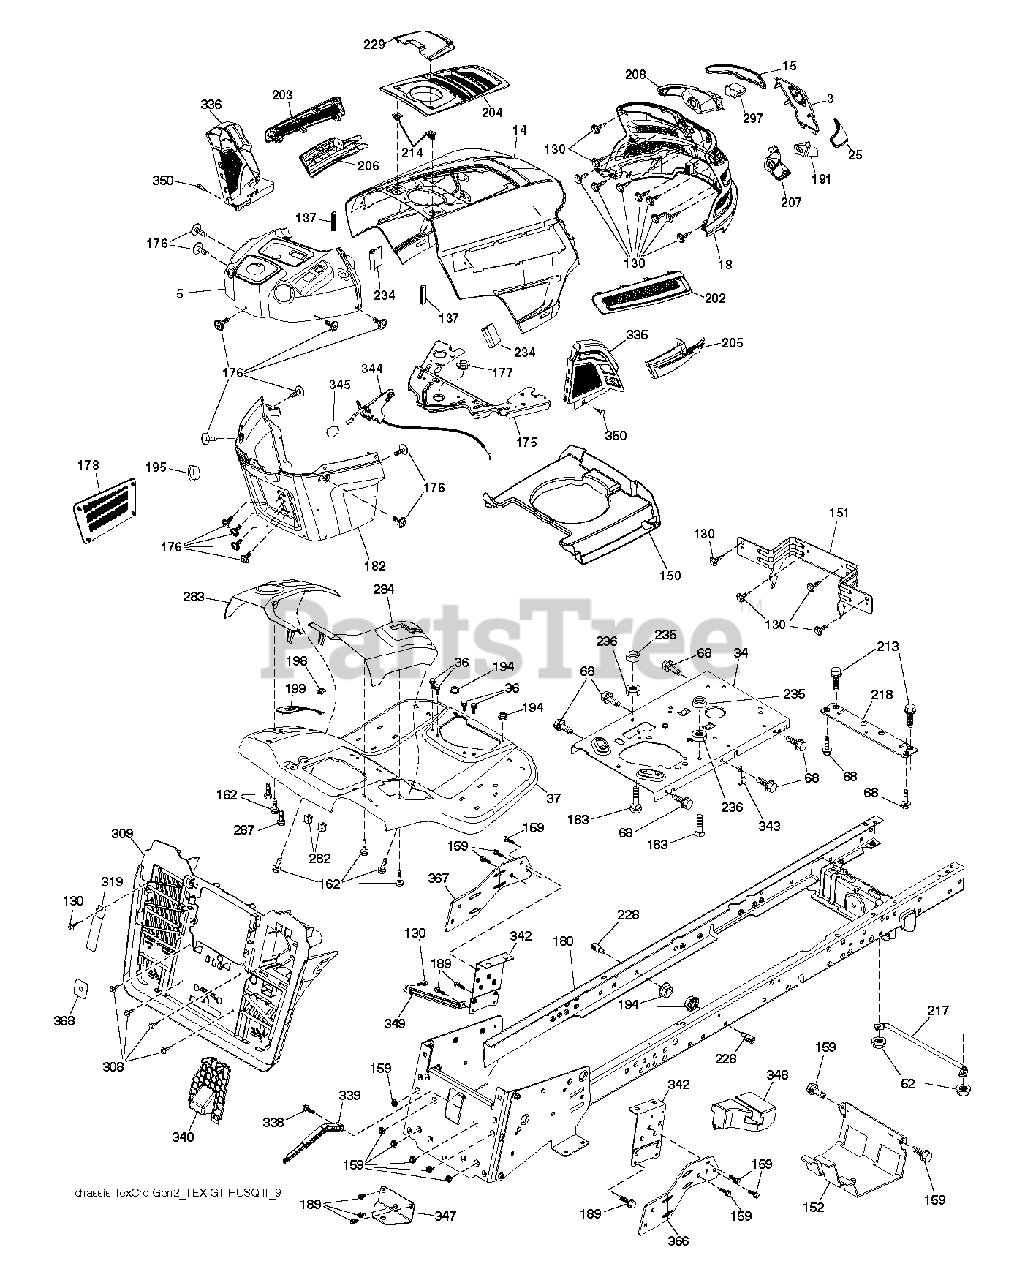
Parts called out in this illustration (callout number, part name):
3	APPLIQUE.SUBASM.GT.HUSQ.II
14	HOOD.ASM.HUSQVARNA.GT.TEX.ORAN
15	LENS.HEADLIGHT.LH.GTII.2011
18	GRILLE.SUBASM.GT.HUSQ.II
25	LENS.HEADLIGHT.RH.GTII.2011
34	PLATE.ENGINE.WELDED.CHASSIS
36	SCREW 5/16"
37	FENDER.TEX.SRD.CRD.BASE
52	LOCKNUT
68	SCREW LT
130	SCREW.#10 X 0.750.BOS
137	BUMPER DASH
150	AIR.DUCT.GTV.BLACK
151	BRACKET.PIVOT.HOOD.GT.HUSQ.II
152	SHIELD.BROWNING.PNT.GT.V2
159	SCREW, 3/8-16X3/4
162	SCREW.HI-LO.CONSOLE
175	PLATE.CROSSMEMBER.HUSQ
176	SCREW.#10-24X5/8.RN.QU
177	BUSHING, STEERING
178	CARGO.ASM.NET.TXGT.W/C
182	DASH DASH LOWER
183	BOLT.5/16-18X1-1/4 FULL THD
189	SCREW
191	INSERT.REFLECTIVE.RH.HUSQ.GTII
194	NUT LOCK HEX FLANGE 5/16-18
195	PLUG.HOLE.DASH.LOWER.12V.BLK
198	INDICATOR.DECK.LIFT.RED
199	PLATE DECK LIFT
202	VENT.SIDE.RH.GT.HUSQ.II.
203	VENT.SIDE.LH.GT.HUSQ.II.498
204	VENT.TOP.EXTERNAL.FILL.GT2.GRE
205	SIDE.TRIM.RH.GT.HUSQ.II
206	SIDE.TRIM.LH.GT.HUSQ.II.GRAY
207	BEZEL LIGHT.RH.GT.II.MYLAR
208	BEZEL LIGHT.LH.GT.II.MYLAR
213	BOLT
214	CLIP.RETAINER.TINNER.
217	ROD.PIVOT.HOOD
218	X-PIECE.HOOD.STOP.NON/
228	STUD.FASTNER.W/ANTI-ROTATE
229	LID.EXT.FILL.GT.HUSQ2.BLACK
234	BUMPER.HOOD.TEX.HUSQVARNA
235	SPACER FENDER
236	NUT.CENTERLOCK.5/16-
282	CLIP.RETAINER.CONSOLE.LT.HUSQ
283	CONSOLE.DECKLIFT.CRDII.498
287	SCREW 1/4X20
297	INSERT.REFLECTIVE.LH.HUSQ.GTII
308	BOLT, 5/16-18 X 1 3/4
309	BACKPLATE.SUBASM.SERV.TEX.CRD.
319	LEVER.BAGGER.TEX.CRD.GEN.BLACK
335	COVER.LOWER.DASH.RH.BLACK
336	COVER-LH.LOWER.DASH.GT2.BLACK
338	BOLT BOLT SHOULDER
339	.WITCH.FULL BAGGER.INDICATOR
340	BATTERY.DOOR.TEX.CRD.GEN.2,1
342	SUPPORT SUPPORT FENDER
343	CLIP CLIP
344	CONTROL.EZ.MULCH.TEX/CRD
345	RP KNOB.OVAL.TAPERED.3/8-16BLK
347	HITCH HITCH TOW TEX CRD GEN 2
349	BRACKET.SUPPORT.LRVB/CRD
350	CLIP.X-MAS.TREE
366	BRACKET.RH.FRONT.BAGGER.BLACK
367	BRACKET.LH.FRONT.BAGGER.BLACK
368	FULL.LEVER.BAGGER.TEX.CRD
